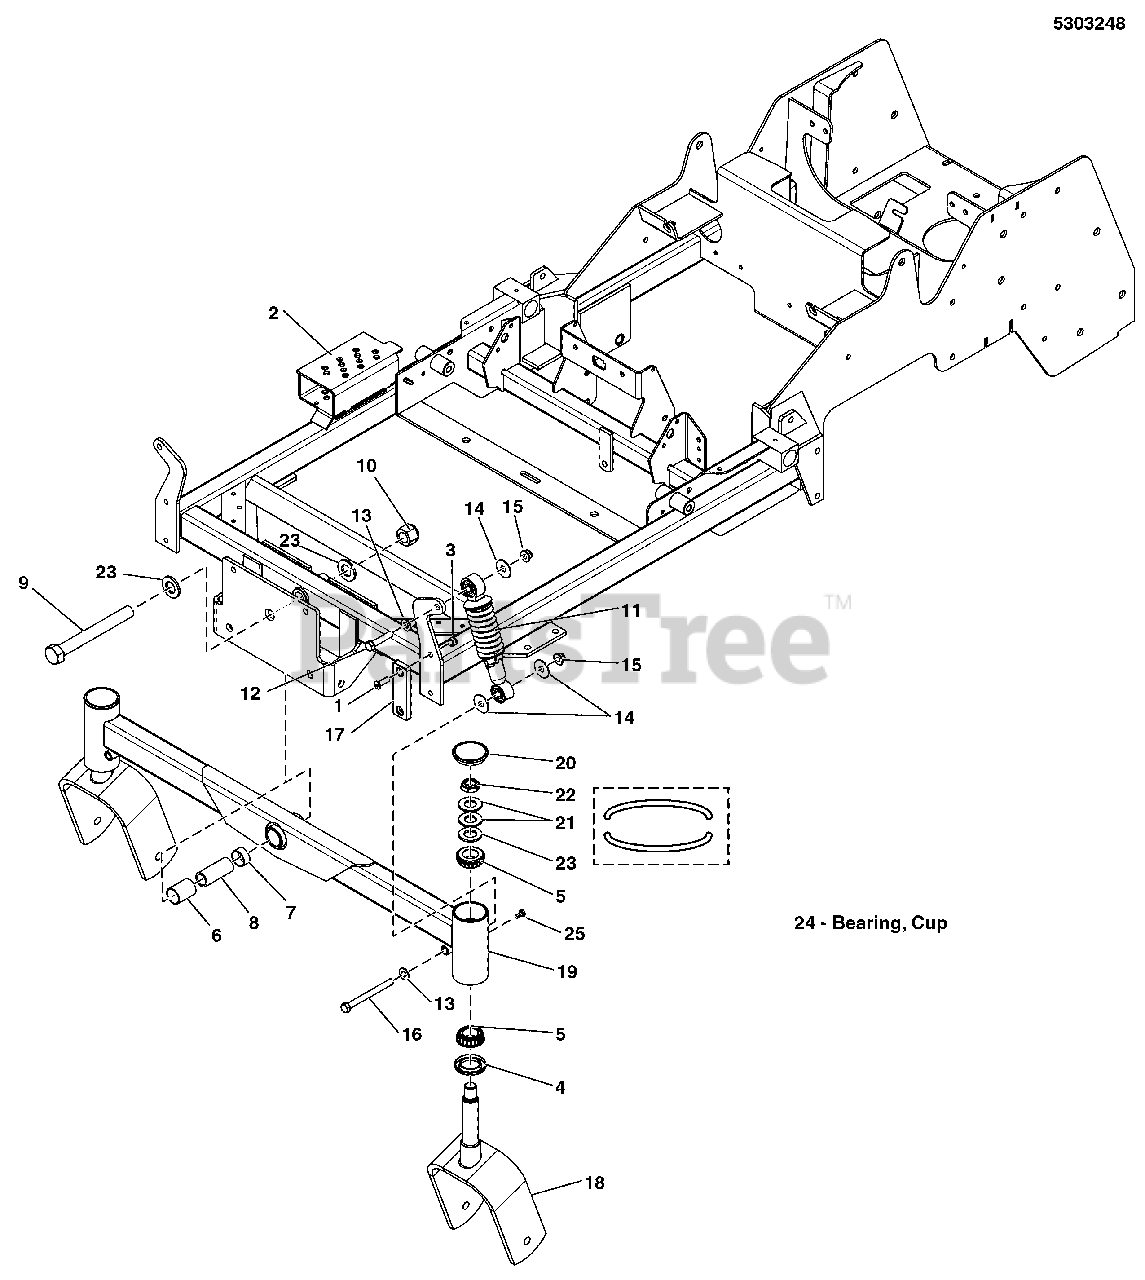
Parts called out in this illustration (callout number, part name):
1	SCREW, 5/16-18 X 1, PHILLIPS HD, BZ
2	WELD, MAIN FRAME, CHAMPION XT - ORG
3	NUT, 5/16-18 HEX NYLON LOCK
4	SEAL, GREASE
5	BEARING, TAPERED ROLLER, 1
6	PIVOT BEARING-1.00 X 1.125 ODX1.50
7	PIVOT BEARING, 1.00 X 1.125 OD X .50
8	SPACER, .75 X 1.00 X 2.38
9	BOLT, 3/4-16 X 6-1/2 YZ GD8
10	NUT, 3/4-16 HEX NYLON LOCK
11	SHOCK, SPRING ASSEMBLY
12	BOLT, 3/8-16 X 1-3/4 GD5
13	WASHER, 3/8 SAE
14	WASHER-3/8 FENDER
15	NUT, 3/8-16 HEX NYLOCK FLANGE
16	BOLT, 3/8-16 X 4 GD5 YZ
17	PAD, FRICTION - 1.25 X 4.00
18	WELD, CASTER YOKE, EVOLUTION - ORG
19	WELD, FRONT PIVOT, CITATION - ORG
20	CAP, LOW PROFILE, STEEL
21	WASHER, BELLEVILLE - 1.500 X .755
22	NUT, 3/4-16, HEX JAM NYLON LOCK
23	WASHER, 3/4 SAE
24	BEARING, CUP
25	BOLT, 1/4-2/ X 1/2, GD5 YZ
